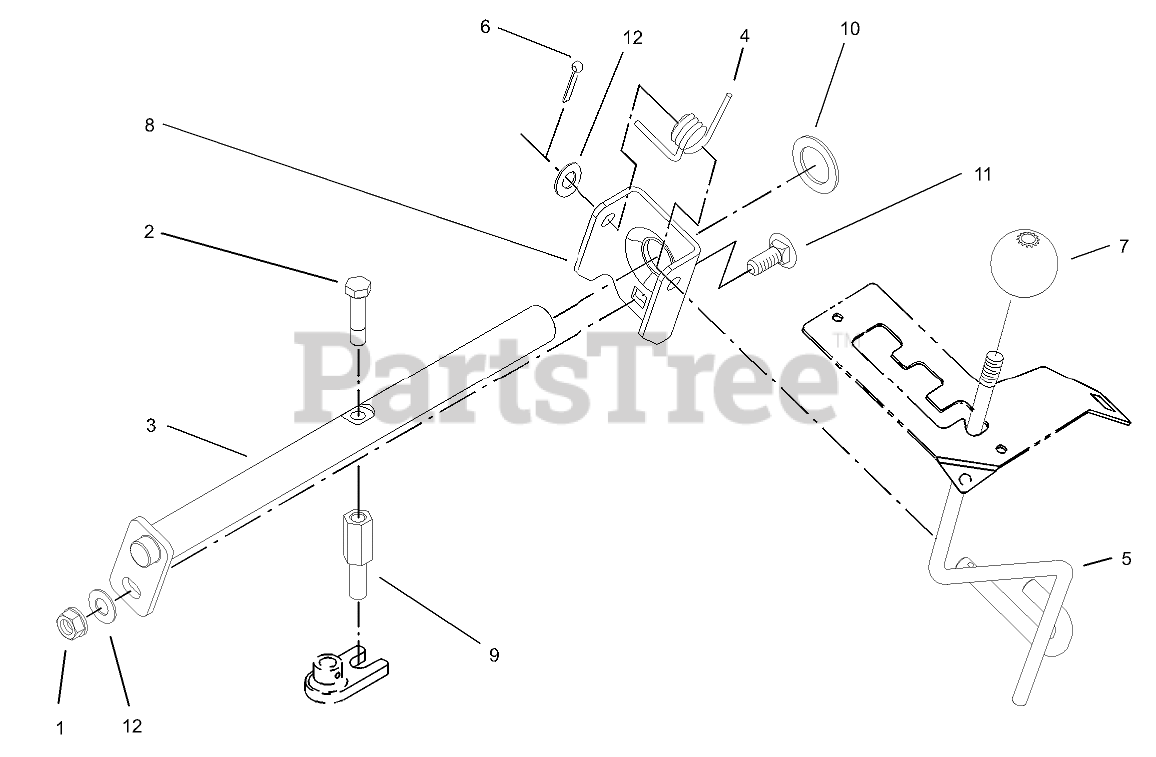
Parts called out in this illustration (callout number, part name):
1	NUT-LOCK, NI
2	SCREW-THREAD LOCKING
3	SHIFT ROD ASM
4	SPRING-TORSION
5	LEVER-SHIFT
6	PIN-COTTER
7	KNOB-HI / LO SHIFT
8	BRACKET-PIVOT
9	ROD-PIVOT, SHIFT
10	SPACER
11	SCREW-CARR
12	WASHER-FLAT
